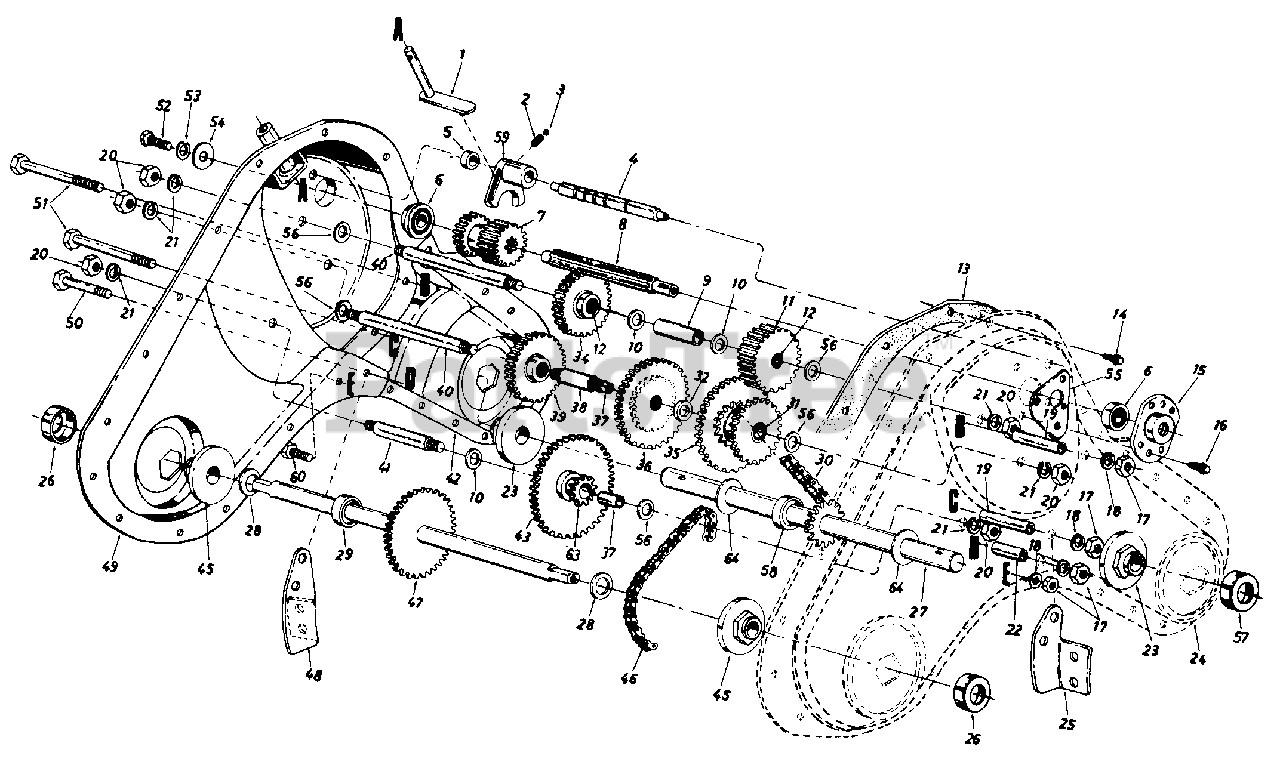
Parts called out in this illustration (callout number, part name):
1	Shifting Bracket Ass'y.
2	Compression Spring .50" Lg.
3	Ball Detent .250" Dia.
4	Detent Shaft 1/2" Dia.
5	Spacer .505" I.D. x .88" O.D.
6	Ball Brg. .62" I.D. x 1.38"
7	Spur Gear 16T
8	Input Spline Shaft 7181'
9	Spacer .657" I.D. x 2.85" Lg.
10	Fl-Wash. .640" I.D. x 1.24
11	Spur Gear 30T 718" I.D.
12	Needle Bearing 518" I.D.
13	Gasket-Trans. Hsg.
14	Hex Wash. S-Tap Scr. 1/4-20 x.50" Lg.
15	1-3/8" Dia. Bearing Housing
16	Hex TT-Tap Scr. 1/4-20 x .75"
17	Hex Nut 5/16-18 Thd.
18	L-Wash. 5/16" I.D.
19	Spacer 1.56" Lg.
20	Hex Nut 7/16-20 Thd.
21	Bell-Wash. .45" I.D. x 1.0"
22	Spacer 1.015" Lg.
23	Tine Shaft Brg. 1.002 x 2.50
24	Trans. Housing Ass'y.-L.H.
27	Tine Shaft Ass'y. 1" O.D.
28	Fl-Wash. .751" I.D. x 1.5" O.D.
29	Spacer .75" I.D. x .50" Lg.
30	Chain #50 5/8 Pitch x 52 Links-Endless
31	Needle Bearing 518" I.D.
32	Fl-Wash. 518" I.D.
34	Spur Gear 30T 12/16" I.D.
35	30/44T Gear Ass'y. Comp.
36	Spur Gear 44T
37	Sleeve Bearing
38	Gear Hub 3/4" I.D. x 3" Lg.
39	Spur Gear 30T 1.0" I.D. x 1/2" W
40	Jack Shaft 5/8" Dia. x 5"
41	Jack Shaft 5/8" Dia. x 2.38"
45	Wheel Brg. .752" x 2.5"
46	#420 Chain 1/2 Pitch x 50 Links-Endless
47	Wheel Shaft Ass'y. 15.6"
51	Hex Bolt 5/16-18 x 2.5"
52	Hex Bolt 1/4-20 x .62" Lg.
53	L-Wash. 3/8" I.D.
54	Fl-Wash. 1/4" I.D. x .93" O.D.
55	Gear Positioner Bracket
56	Fl-Wash. 7/16" I.D. x 1-3/8"
57	Dust Cover Ass'y. 1" Shaft
58	Spacer 1" I.D. x 2" O.D.
59	Shifting Fork
60	Hex Bolt 5/16-18 x .75" Lg.
63	1OT Sprocket Ass'y.
64	Thrust Wash. 1.03" I.D. x 1.62" O.D.
